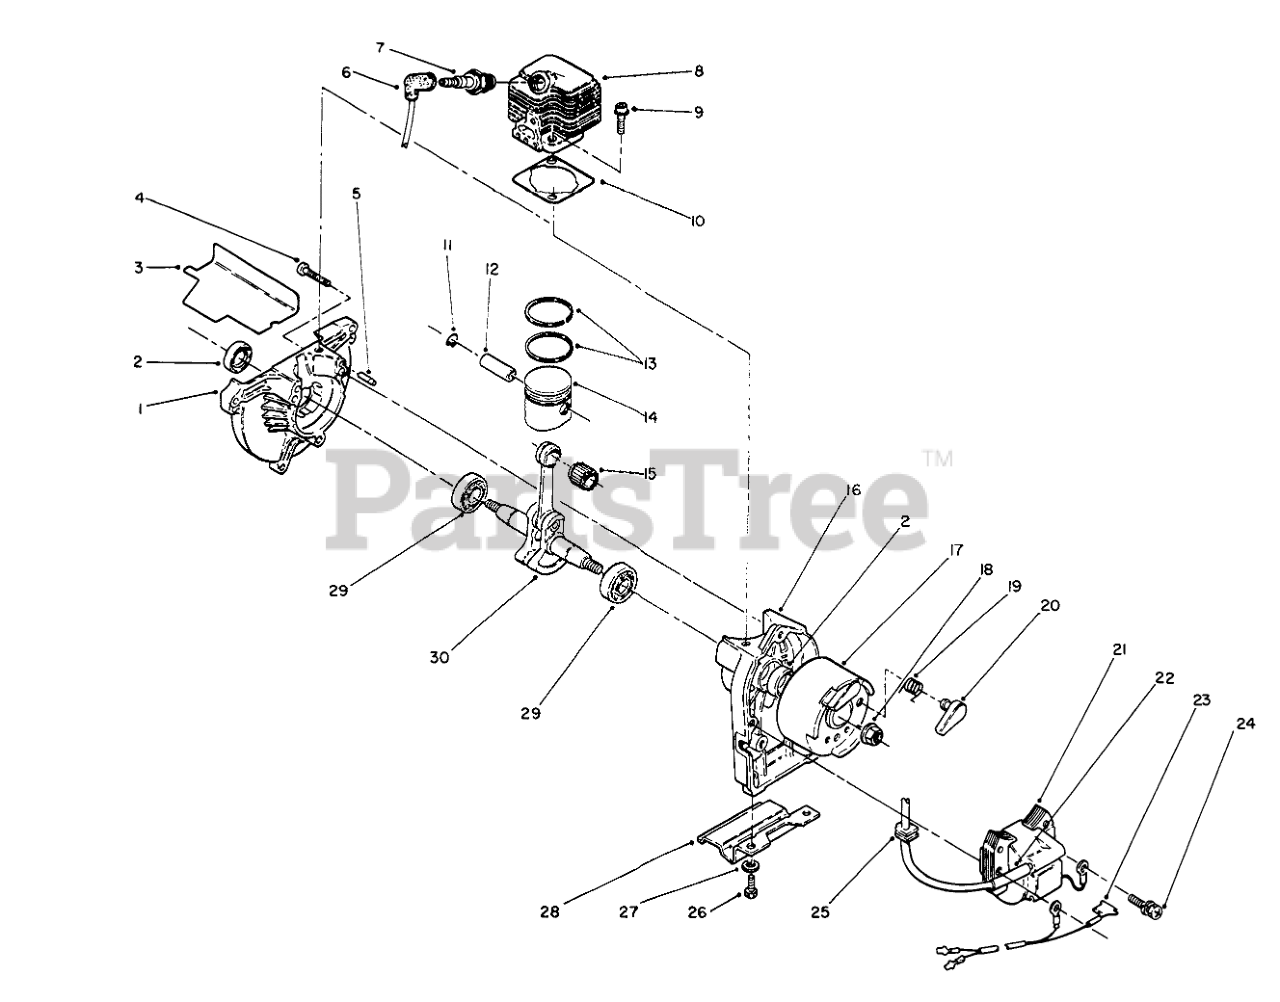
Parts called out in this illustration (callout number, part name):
1	DRIVE CASE
2	OIL SEAL
3	BAFFLE GASKET
4	Screw
6	PLUG BOOT
7	Plug-Spark
8	CYLINDER
9	FLANGE BOLT
10	CYL GASKET
11	PISTON PIN CLIP
12	Pin-Piston
13	TOP RING
14	Piston Assembly (Incl. Ref. #12)
15	NEEDLE BEARING
16	STARTER CASE
17	Flywheel Assembly (Incl. Ref. #19 & 20)
19	RETURN SPRING
20	RATCHET
21	IGNITION COIL
23	LEAD WIRE
24	BOLT AND WASHER
25	GROMMET
26	M6 X 1 X 1/2 MWH SCREW
27	WASHER-LOCK
28	STAND SUPPORT
29	BEARING
30	CRANKSHAFT ASSEMBLY
